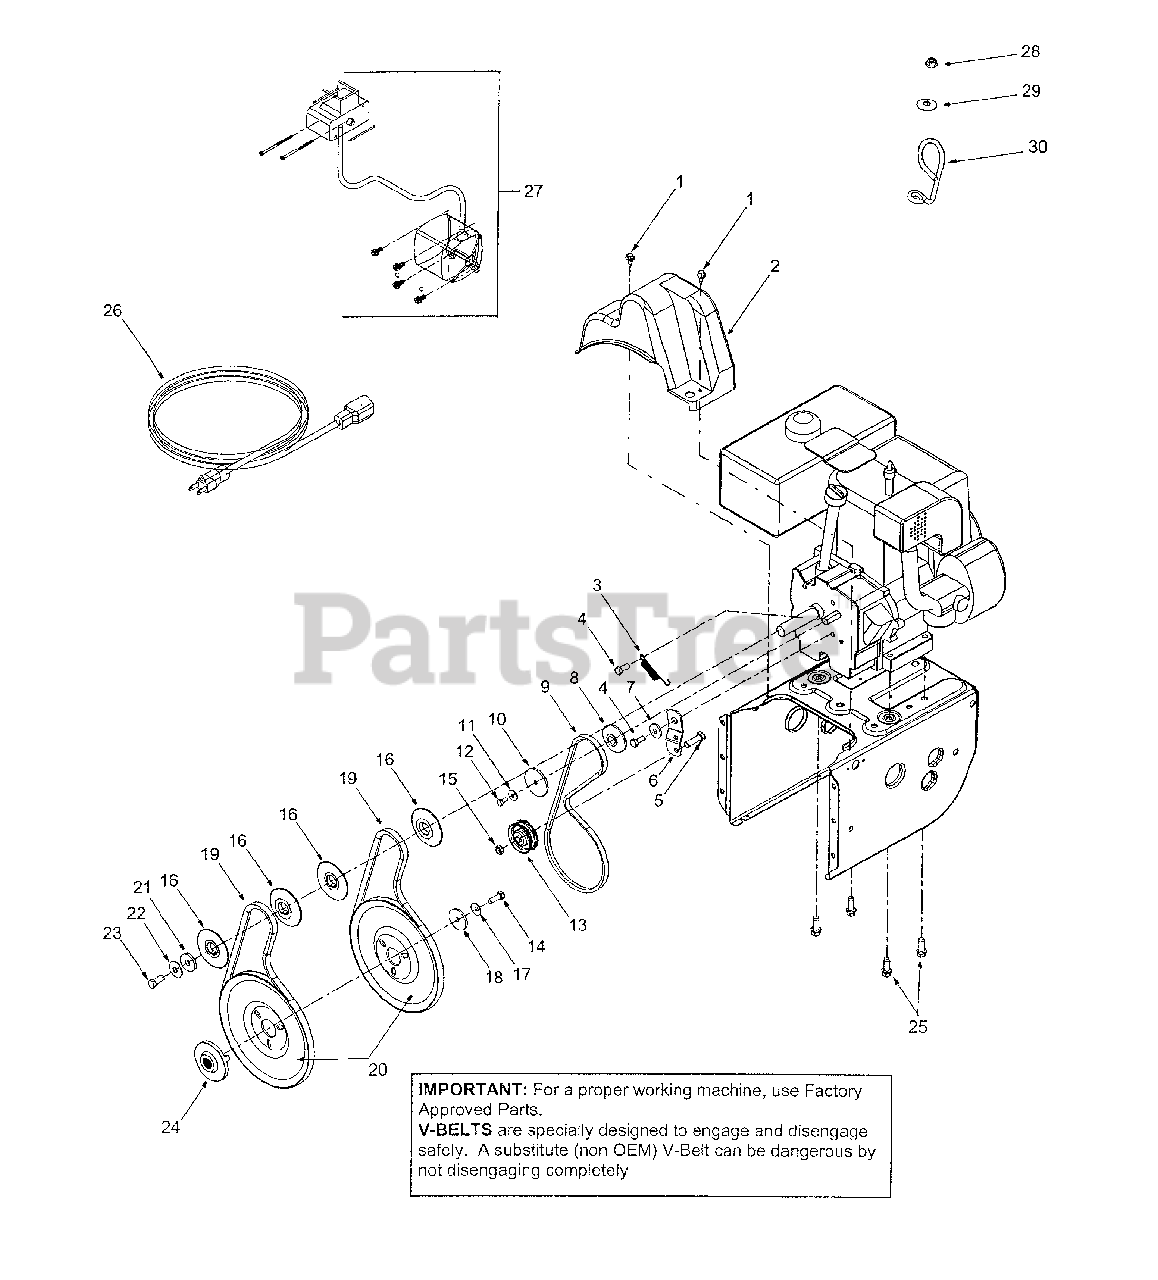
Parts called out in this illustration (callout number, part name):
1	Hex Washer Screw 1/4-20 x .625
2	Belt Cover
3	Extension Spring
4	Hex Screw 5/16-24 x .75
5	Hex Cap Screw 3/8-16 x 1.25
8	Pulley Half
9	V-Belt
10	Pulley Half
11	Bell Washer
12	Hex Cap Screw 1/4-28 x .50
13	Flat Idler
14	Lock Hex Cap Screw 5/16-24
15	Lock Jam Nut 3/8-16
16	Pulley Half
17	Bell Washer
18	Flat Washer
19	Belt
20	Auger Pulley
21	Flat Washer 3/8 x 1.25 OD
22	Bell Washer
23	Hex Cap Screw 3/8-24
24	Adapter Pulley
25	Hex Screw 3/8-16 x 1.0
26	Extension Cord
27	Electric Start Kit
28	Lock Nut, 1/4-20
29	Flat Washer, .28 x .74 x .063
30	Cable Guide
